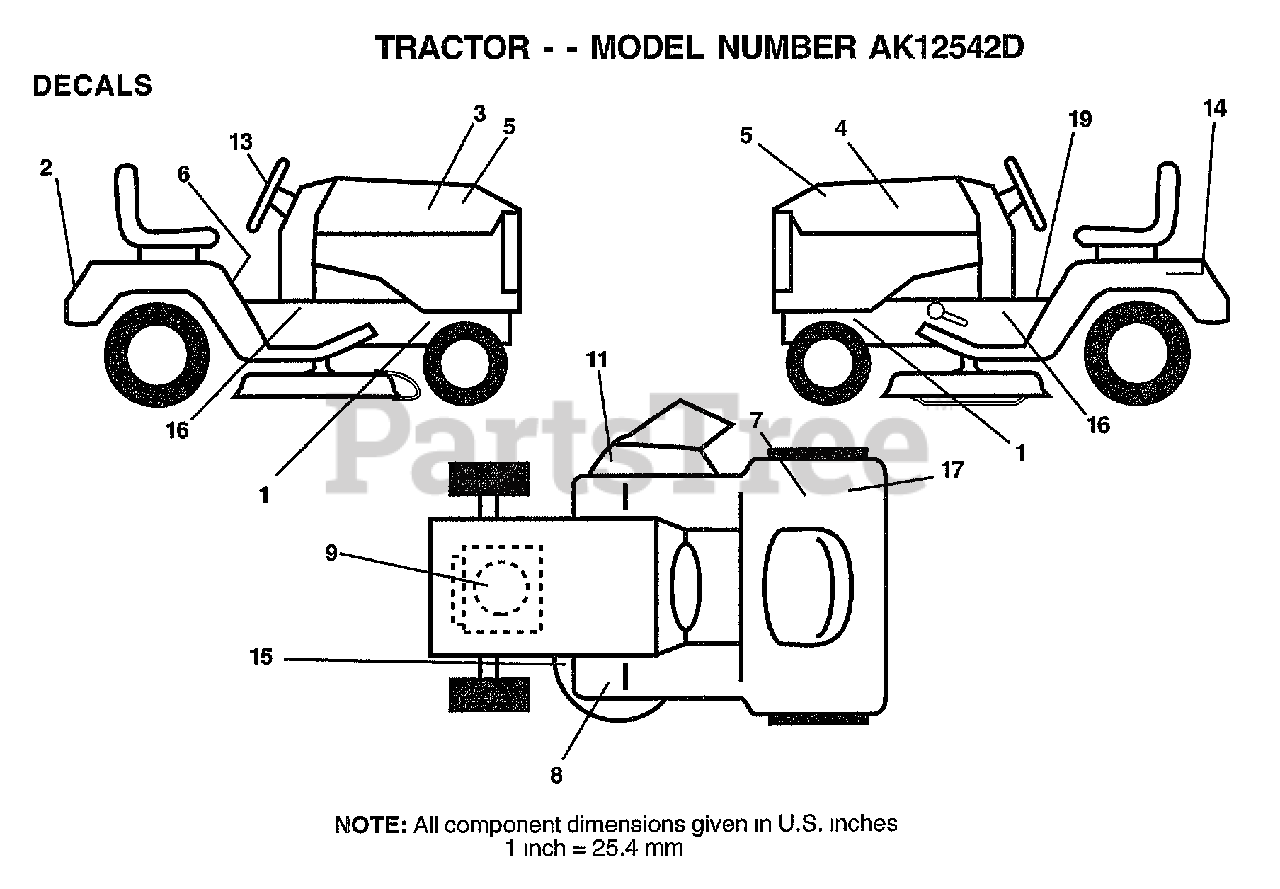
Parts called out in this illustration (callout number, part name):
1	"DECAL CHASSIS,HOT"
2	DECAL FENDER
3	DECAL HOOD RH
4	DECAL HOOD LH
6	DECAL.READ.O.MANU
7	DECAL.EURO.ST.CE.
8	DECAL-BRAKE/CLUTC
9	DECAL, ENGIN
11	DECAL.DANGER.CUTF
13	"DECAL,STR WHL"
14	DECAL.BATRY.3-3908
15	"DECAL-SCHEM,BELT"
16	"DECAL CHASSIS 42"""
19	DECAL BRAK PARK
